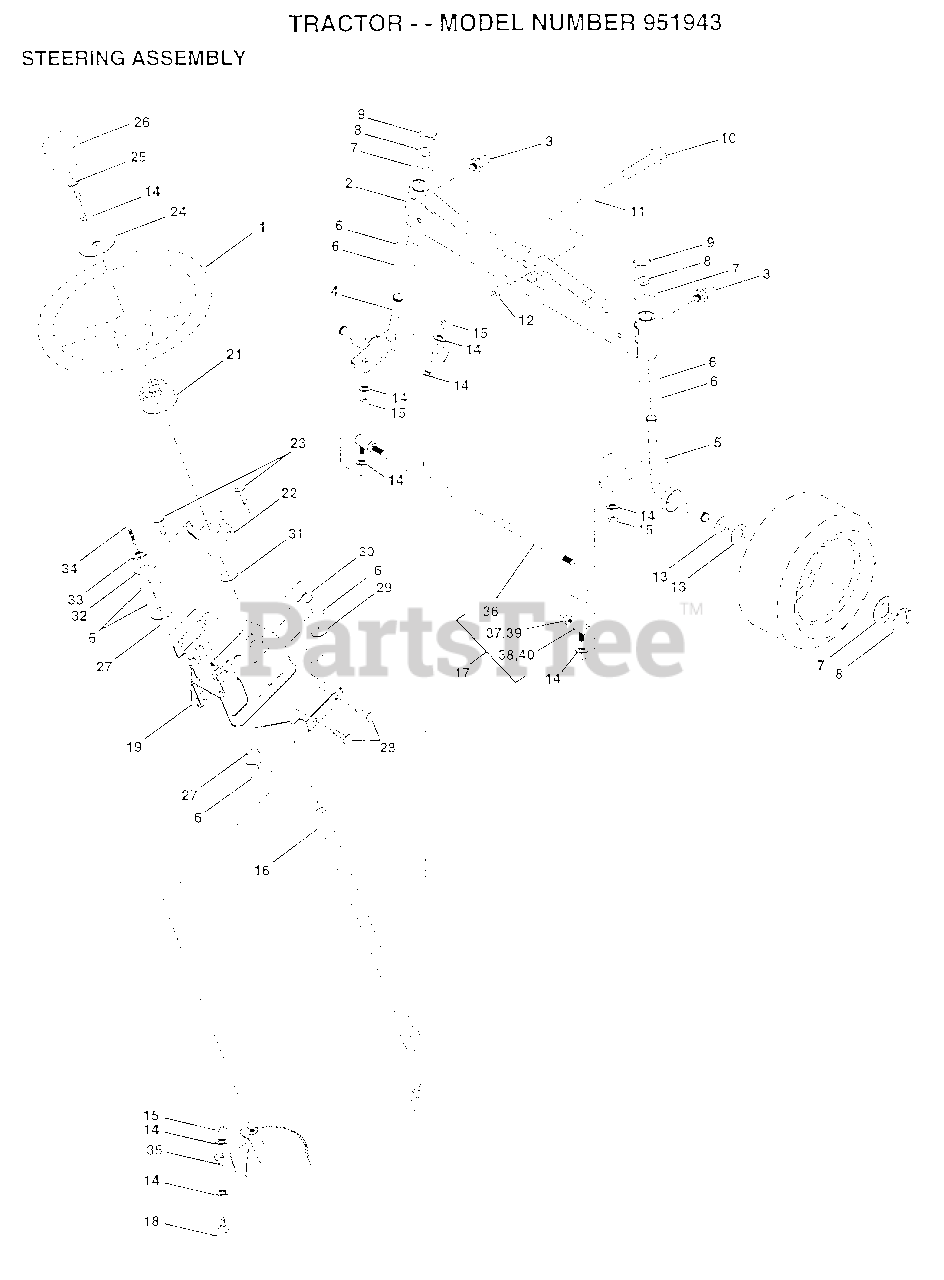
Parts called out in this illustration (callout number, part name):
1	WHEEL STR AYP BLK
3	ZERK M
4	SPINDLE.ASM.LH
6	WASHER .T
7	WASHER
8	RING
9	CAP
10	BOLT
11	SPACER BEARING
12	"NUT-LOC,FLANGE LT"
13	WASHER
14	LOCKWASHER
16	SHAFT.STEER.VGT
17	ROD.ASM.TIE.BALL
18	DRAGLINK.BALL.JOI
21	ADAPTER LT
24	WASHER T
25	BOLT
26	CAP STEER AYP
27	COL. SRTG. BEAR.
28	SCREW
29	"FLANGE GT, BEAR."
30	KLIP RING
31	BUSHING.NYLINER.
32	WASHER
33	LOCKWASHER
34	BOLT
35	GEAR.ASM.SECTOR.
37	NUT
38	JOINT.RH
39	NUT
40	JOINT.LH
